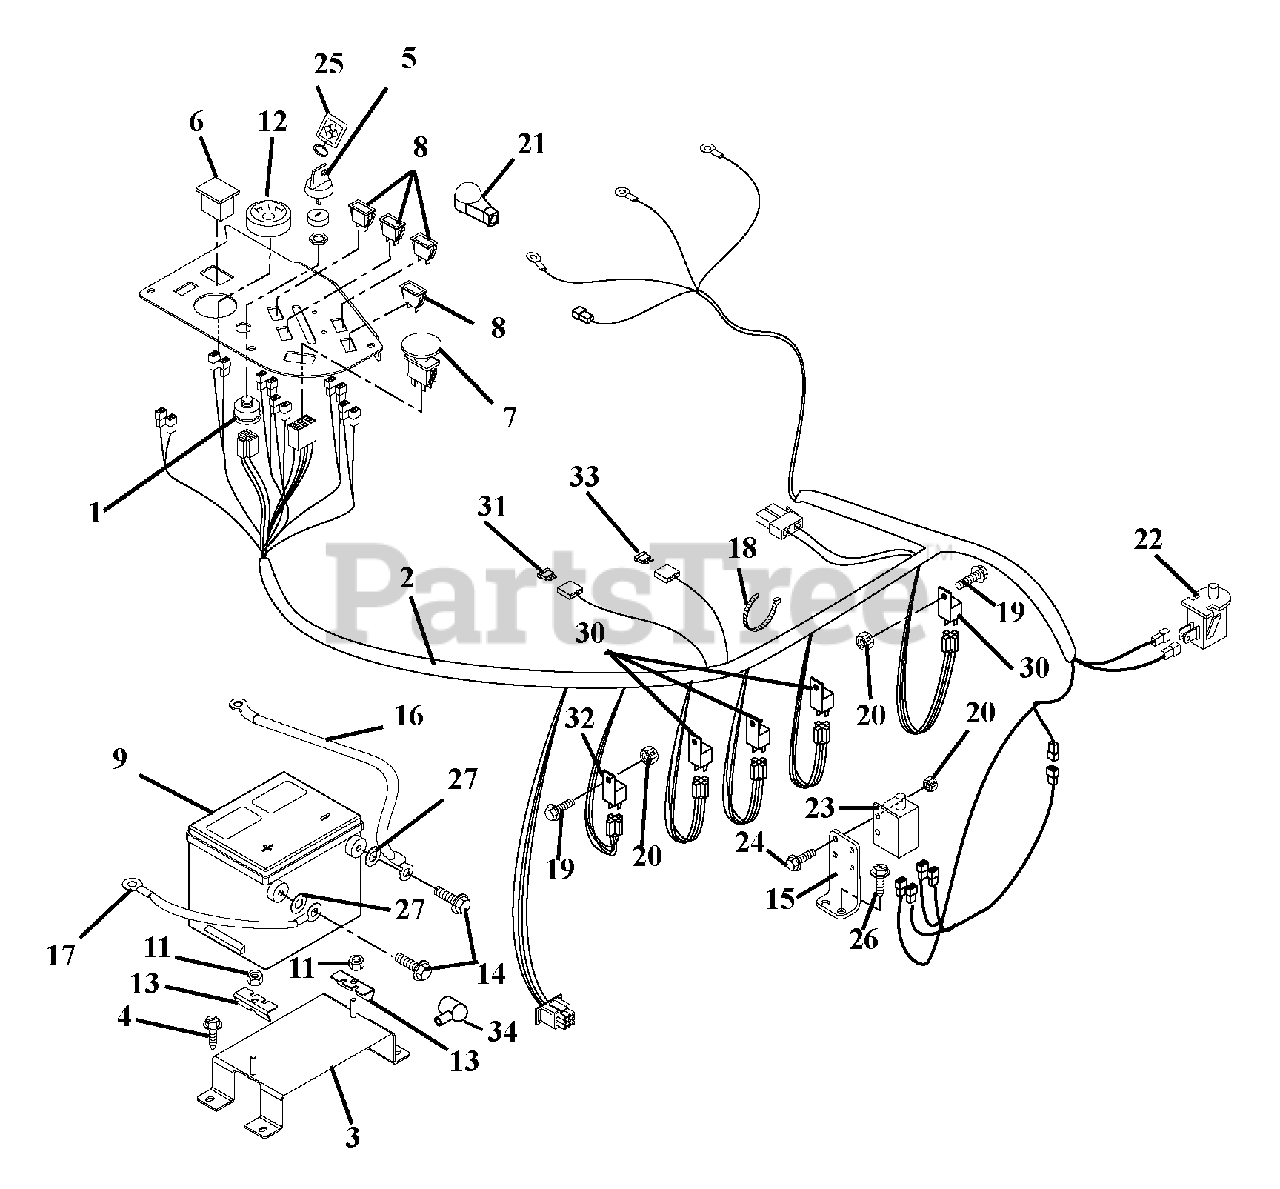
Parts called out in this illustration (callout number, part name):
1	Switch, Ignition
2	Harness, Wiring
3	Weldment, Battery Support
4	Screw-Tapping .38-16 x .75 Hex Washer Head
5	Key-with Cap
5	Ignition Key Set
6	Hour Meter
7	Switch-Clutch With Retainer Ring
8	Light-Indicator
9	Battery with Tube
10	Switch, Blank
11	Nut-Locking-Top-Flange .31-18
12	Gauge, Temperature
13	Bracket, Battery Hold-Down
14	Bolt-Hex .25-20 x .75 Grade 5
15	Mount, Safety Switch
16	Positive Cable
17	Cable, Negative Battery
18	Cable Tie
19	Screw-Machine 10-24 x .75 Hex Washer Head
20	Nut-Locking-Nylon 10-24 With Insert
21	Eyelet Terminal Boot
22	Switch, Snap Mounting (N.O.)
23	Switch-Single Pole
24	Screw-Machine 10-24 x .75 Hex Washer Head
25	Key Chain
26	Screw-Tapping .25-20 x .50 Hex Washer Head
27	Washer-Flat-Steel .406 x 1.00 x ..083
28	Fuse, ATO 15 Amp
29	Diode, Connector Shell
30	Relay
31	Fuse, ATO 30 Amp
32	Pre-Heat Timer
33	Fuse, ATO 60 Amp
34	Boot, Eyelet Terminal
